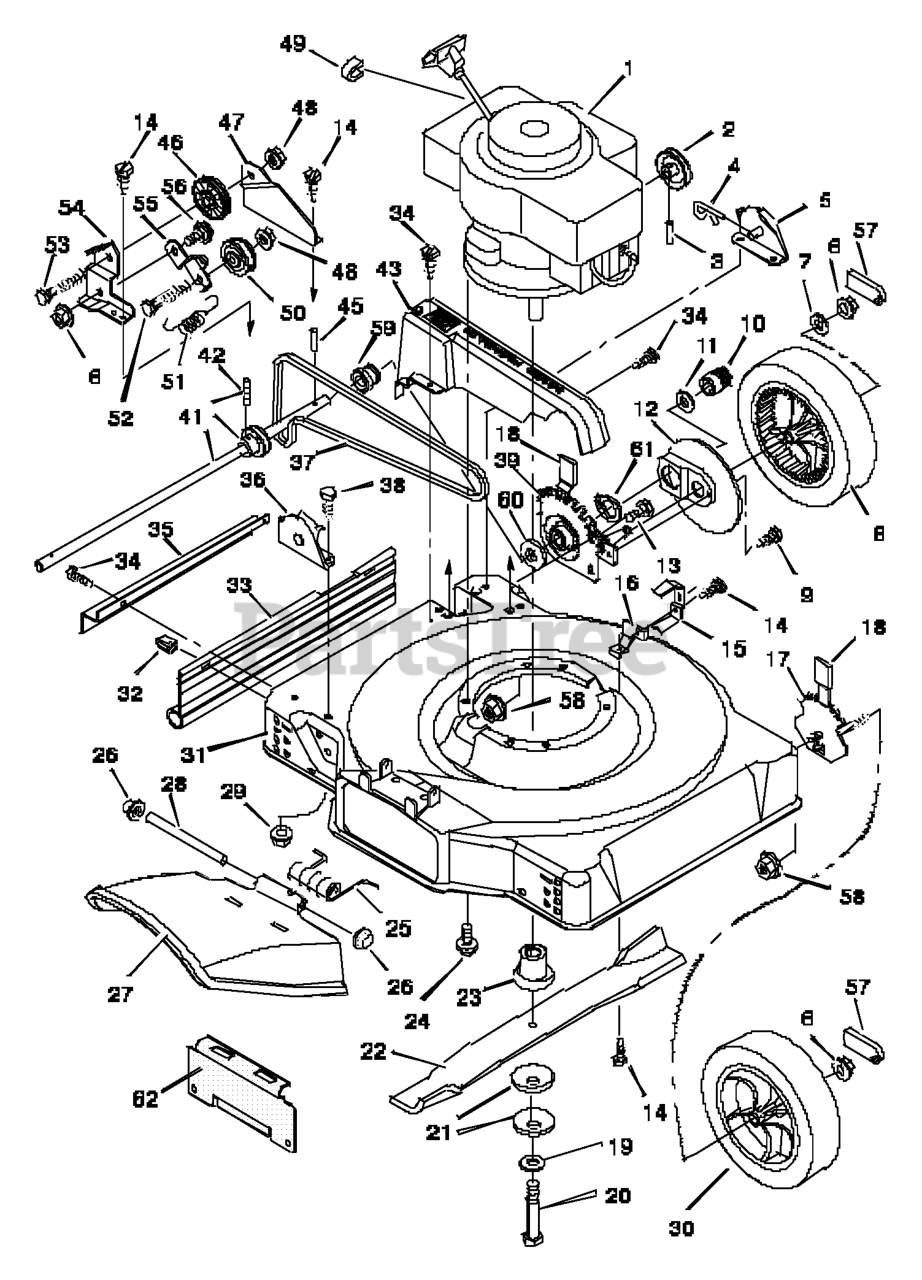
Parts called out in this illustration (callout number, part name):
1	Engine *
3	Pin, Spring
4	Pin, Hair
5	Bracket, Left Handle
6	Nut
7	Washer
8	Wheel, Drive
10	Gear, Right Pinion
11	Washer
12	Cover, Dust
13	Bolt, Hex
15	Guide, Belt
16	Belt Guide, Briggs
21	Washer, Belleville
23	Adapter, Blade
24	Bolt, Engine
25	Spring, Torsion
26	Push On Cap
27	Deflector, Chute
30	Wheel and Tire, Front
31	Housing
32	Retainer
33	Deflector, Rear
35	Guard, Axle
36	Bracket, Right Handle
37	Belt, Briggs & Stratton
39	Height Adjuster, Left
41	Axle, Pulley & Setscrew
42	Setscrew
43	Belt Guard, Briggs
45	Pin, Drive
46	Pulley, Idler
47	Support, Idler
48	Nut
49	Stop, Rope
50	Pulley, Idler
51	Spring, Extension
52	Bolt, Hex
53	Bolt, Hex
54	Bracket, Idler
55	Arm, Idler
56	Bolt, Shoulder
57	Cap, Hub
58	Nut, Flange
59	Bearing and Retainer
60	Washer, Belleville
61	Retainer Ring
62	Plate, Mulcher
